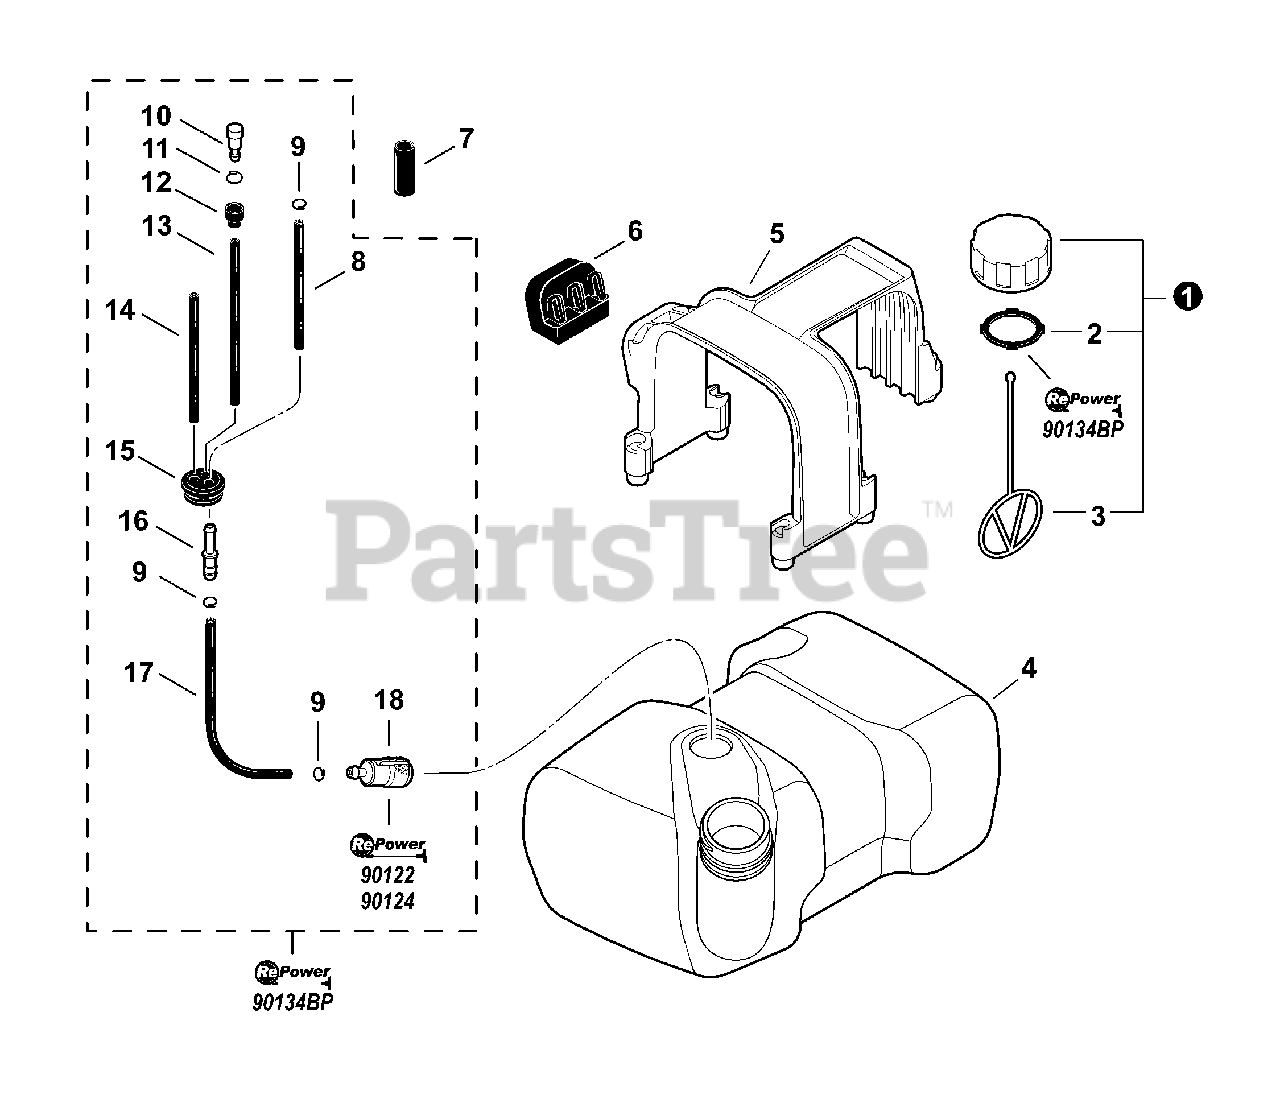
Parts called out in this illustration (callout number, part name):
1	CAP ASSY - ORANGE
2	GASKET, CAP
3	CONNECTOR, CAP
4	TANK, FUEL
5	RETAINER, FUEL TANK
6	CUSHION
7	SLEEVE
8	PIPE - 3×5×135 -- BLACK
9	CLIP - 6
10	VENT, FUEL TANK
11	CLIP - 6.5
12	COVER, VENT
13	PIPE - 3×6×130 -- BLACK
14	PIPE - 2.4×5×200 -- BLACK
15	GROMMET
16	CONNECTOR, FUEL PIPE
17	PIPE, FUEL - BLACK
18	FILTER, FUEL
